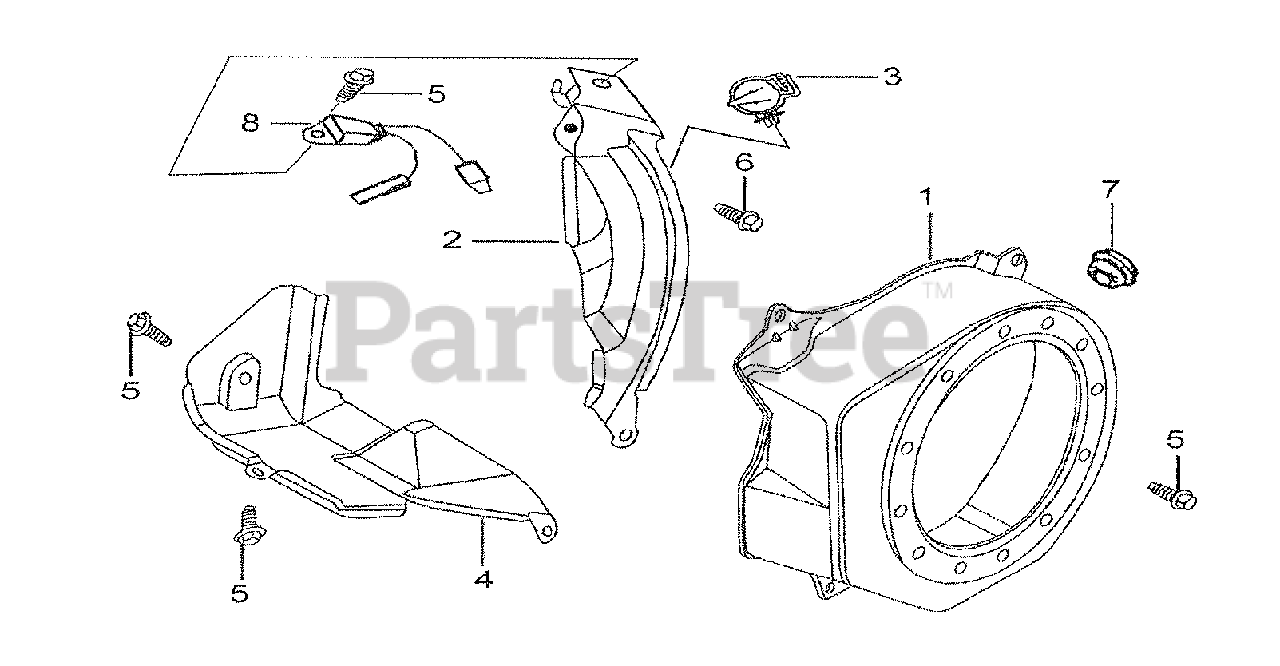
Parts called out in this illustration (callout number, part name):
1	COVER COMPL, FAN(BLUE)
2	PLATE, COMP, SIDE
3	CLAMP, CORD
4	LEAD WIND COVER
5	BOLT, FLANGE 6 X 12
6	BOLT, FLANGE 6 X 20
7	GROMMET 20MM
8	ALERT UNIT, OIL
